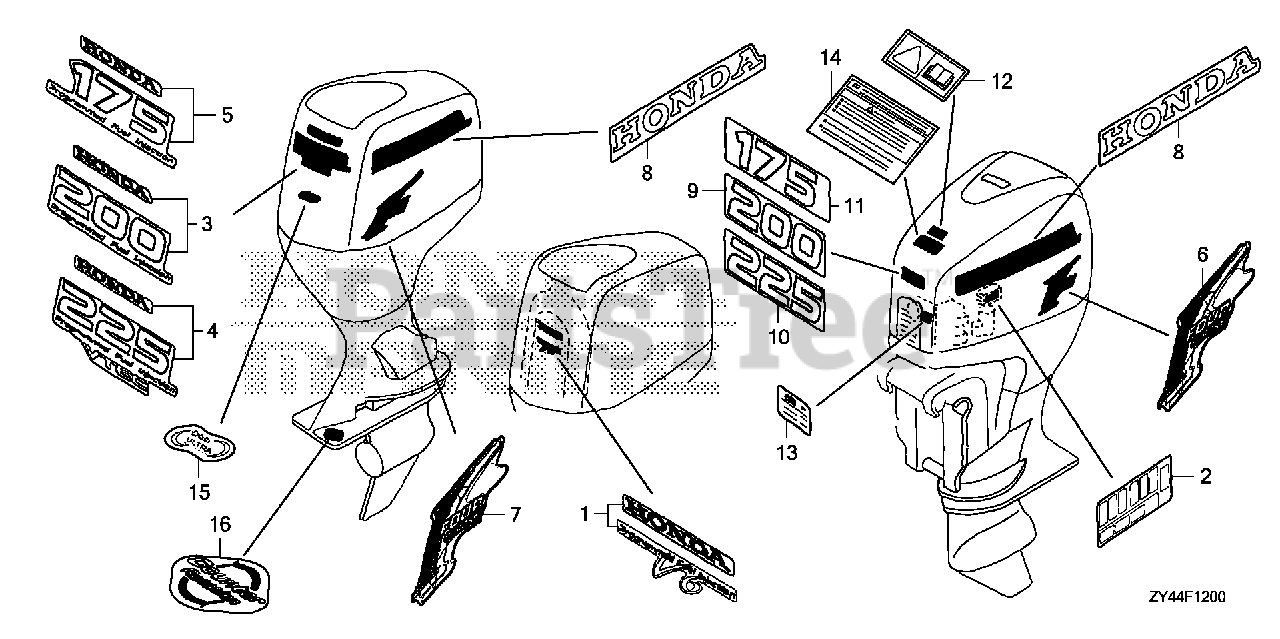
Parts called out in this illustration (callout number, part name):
1	MARK, EMBLEM
2	LABEL, FUSE
4	MARK, RR. (BF225)
6	MARK, SIDE (L. SIDE)
7	MARK, SIDE (R. SIDE)
8	MARK, SIDE STRIPE (HONDA)
10	MARK, FR. EMBLEM (BF225)
13	LABEL, CAUTION OIL (ENGLISH)
14	LABEL, OPERATOR CAUTION (ENGLISH)
14	LABEL, WARNING OPERATOR
16	MARK, COUNTER ROTATION
